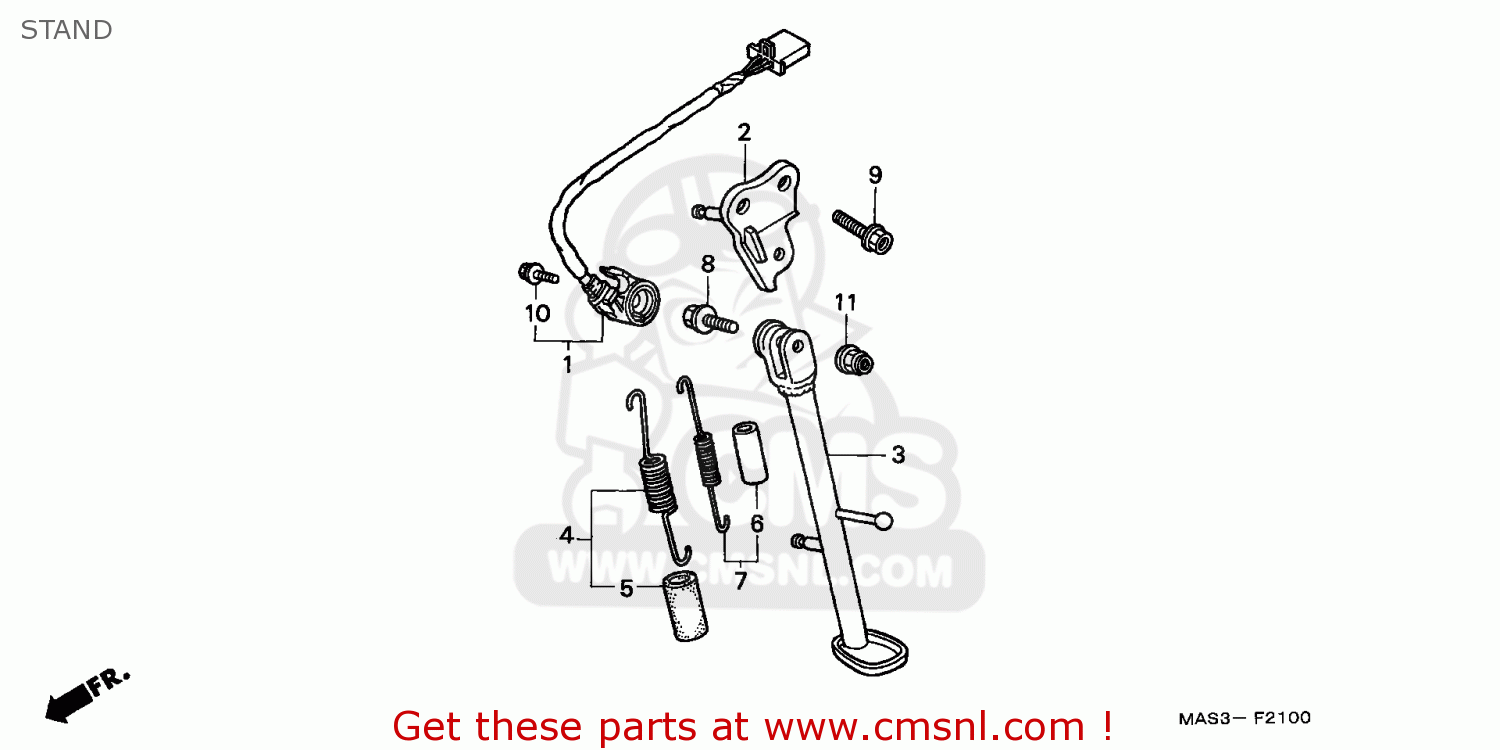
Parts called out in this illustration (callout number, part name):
1	SET,SIDE STAND SW
2	BRKT.SIDE STAND
3	BAR COMP,SIDE STA
4	SPRING ASSY,SIDE
5	TUBE,SIDE STAND S
8	BOLT,SIDE STAND P
9	BOLT,FLANGE,10X32
10	BOLT,SPECIAL 6X16
11	NUT,SIDE STAND
